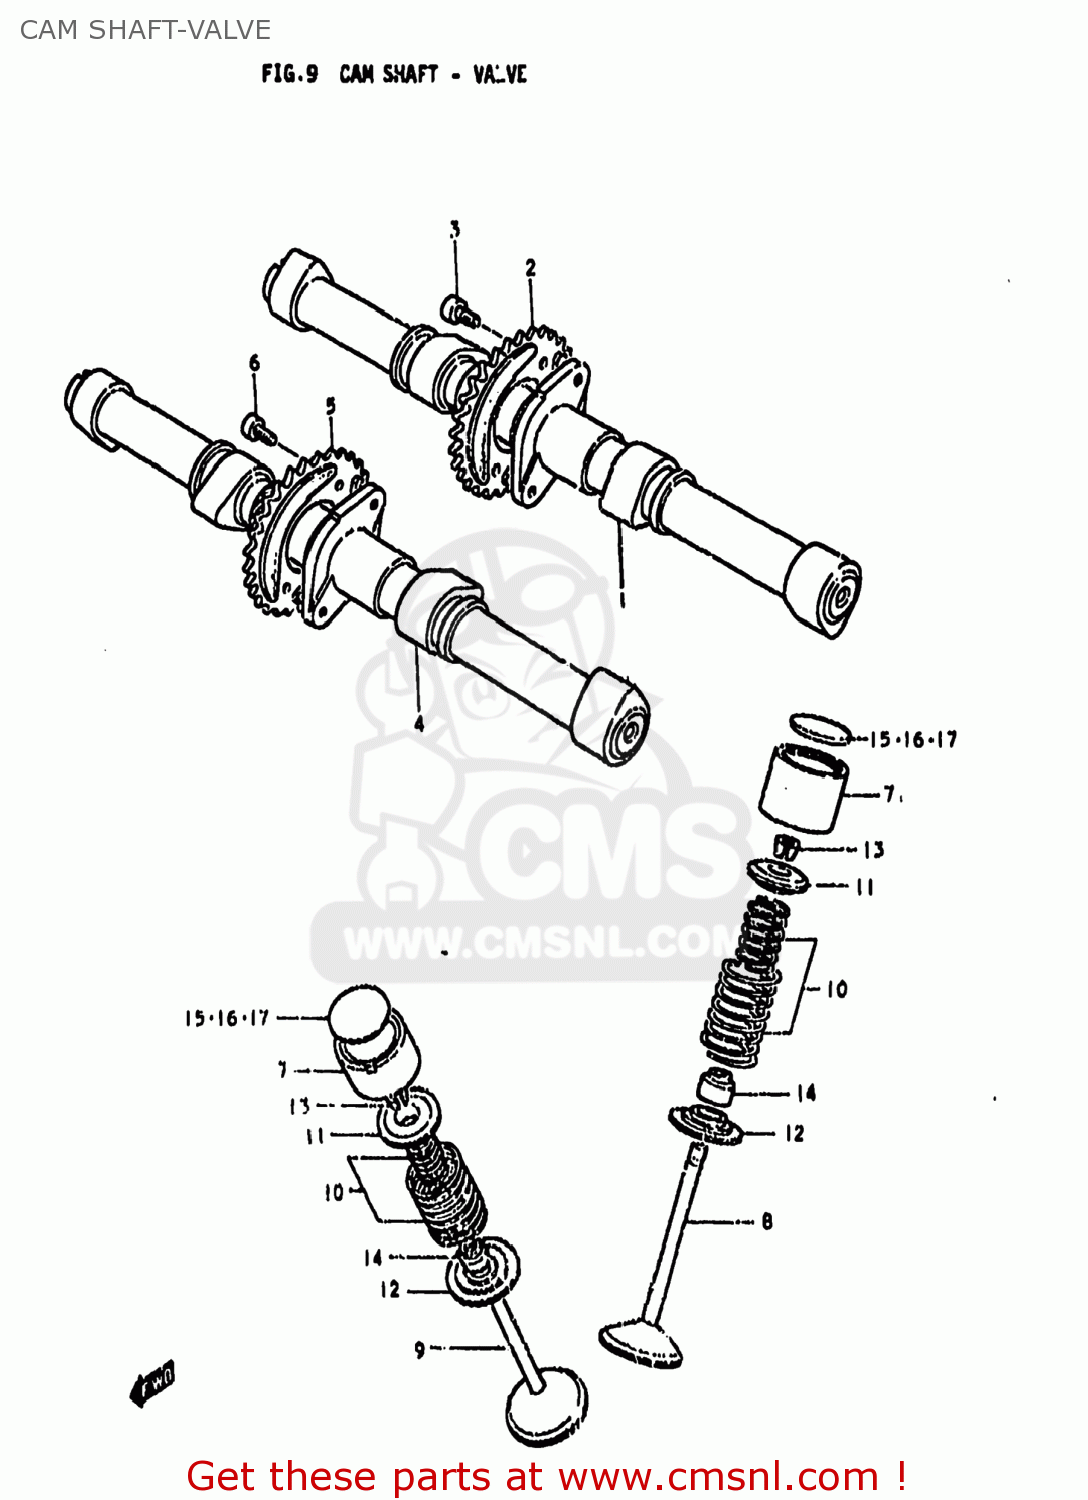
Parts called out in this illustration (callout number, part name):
1	CAMSHAFT
2	SPROCKET,CAMSHAFT
3	BOLT 6X11
4	CAMSHAFT,EXHAUST
5	SPROCKET,EXHAUST CAMSHAFT
6	BOLT 6X11
7	TAPPET
8	VALVE,INTAKE
9	VALVE,EXHAUST
10	SPRING SET,VALVE
11	RETAINER,VALVE SPRING
12	SEAT,VALVE SPRING
13	SHIM,TAPPET
14	SEAL,OIL(7X14.4X9)
15	SHIM,TAPPET
16	SHIM,TAPPET
17	SHIM,TAPPET
18	SHIM SET,TAPPET
19	CASE
